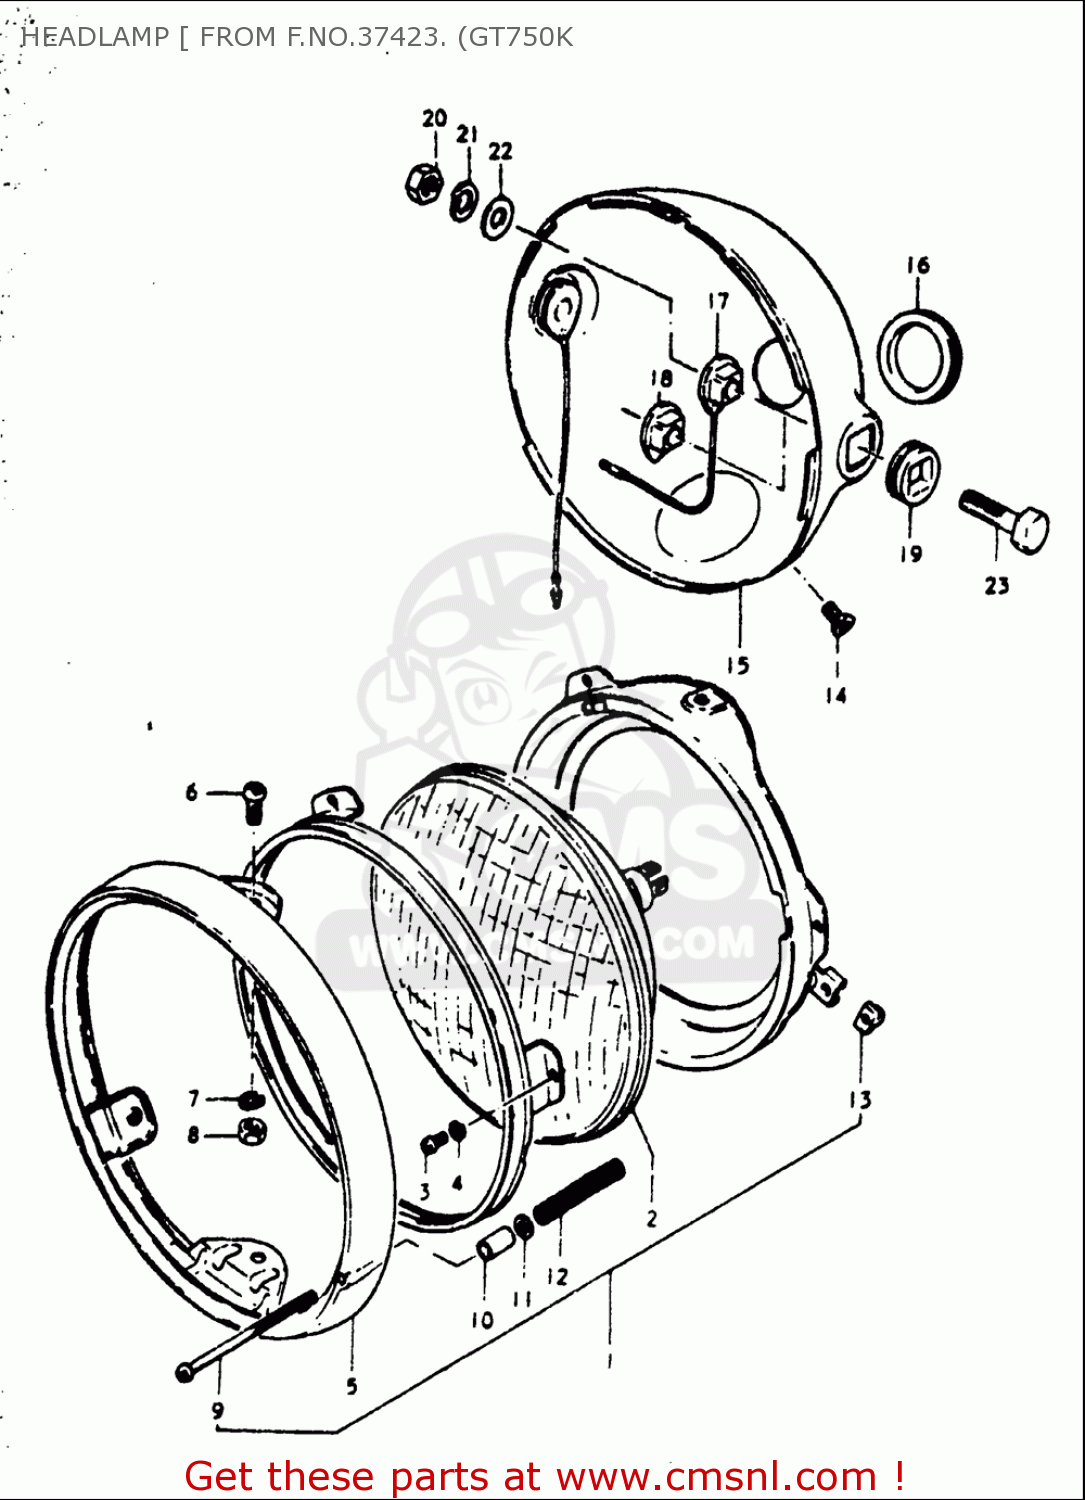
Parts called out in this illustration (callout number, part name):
3	SCREW
4	WASHER,LOCK
5	RIM,HEADLAMP
6	SCREW
7	WASHER,LOCK
8	NUT
9	SCREW
11	WASHER
13	NUT
14	SCREW
15	HOUSING,HEADLAMP
16	CUSHION,HOUSING
17	PIECE,ADJUSTER
19	GROMMET,HEADLAMP HOUSING
20	NUT
21	WASHER,LOCK
22	WASHER
23	BOLT
